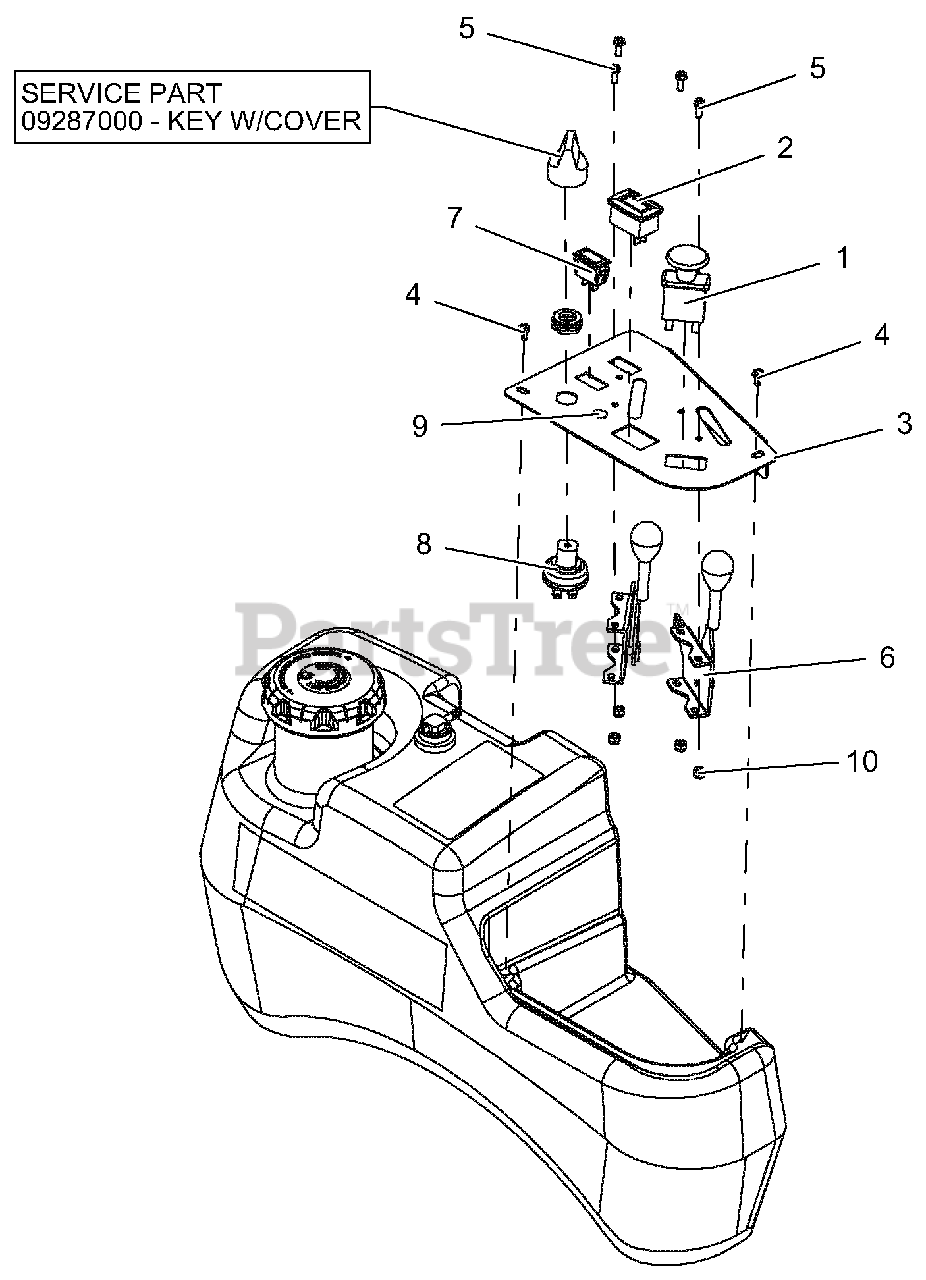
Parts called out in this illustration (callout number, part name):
1	SWITCH, CLUTCH
2	METER, HOUR W/MAINTENANCE
3	PANEL, CONTROL - PROTURN 100 (BLACK)
4	SCR-MCH 10-24X.38 HWHSTAINLESS
5	@SCR-MCH 10-24X.50 HWH YWZC
6	CABLE, THROTTLE
7	LIGHT, INDICATOR
8	SWITCH, IGNITION
9	PLUG, HOLE .50 DIA
10	NUT-LK-NYL #10-24 YWZC
